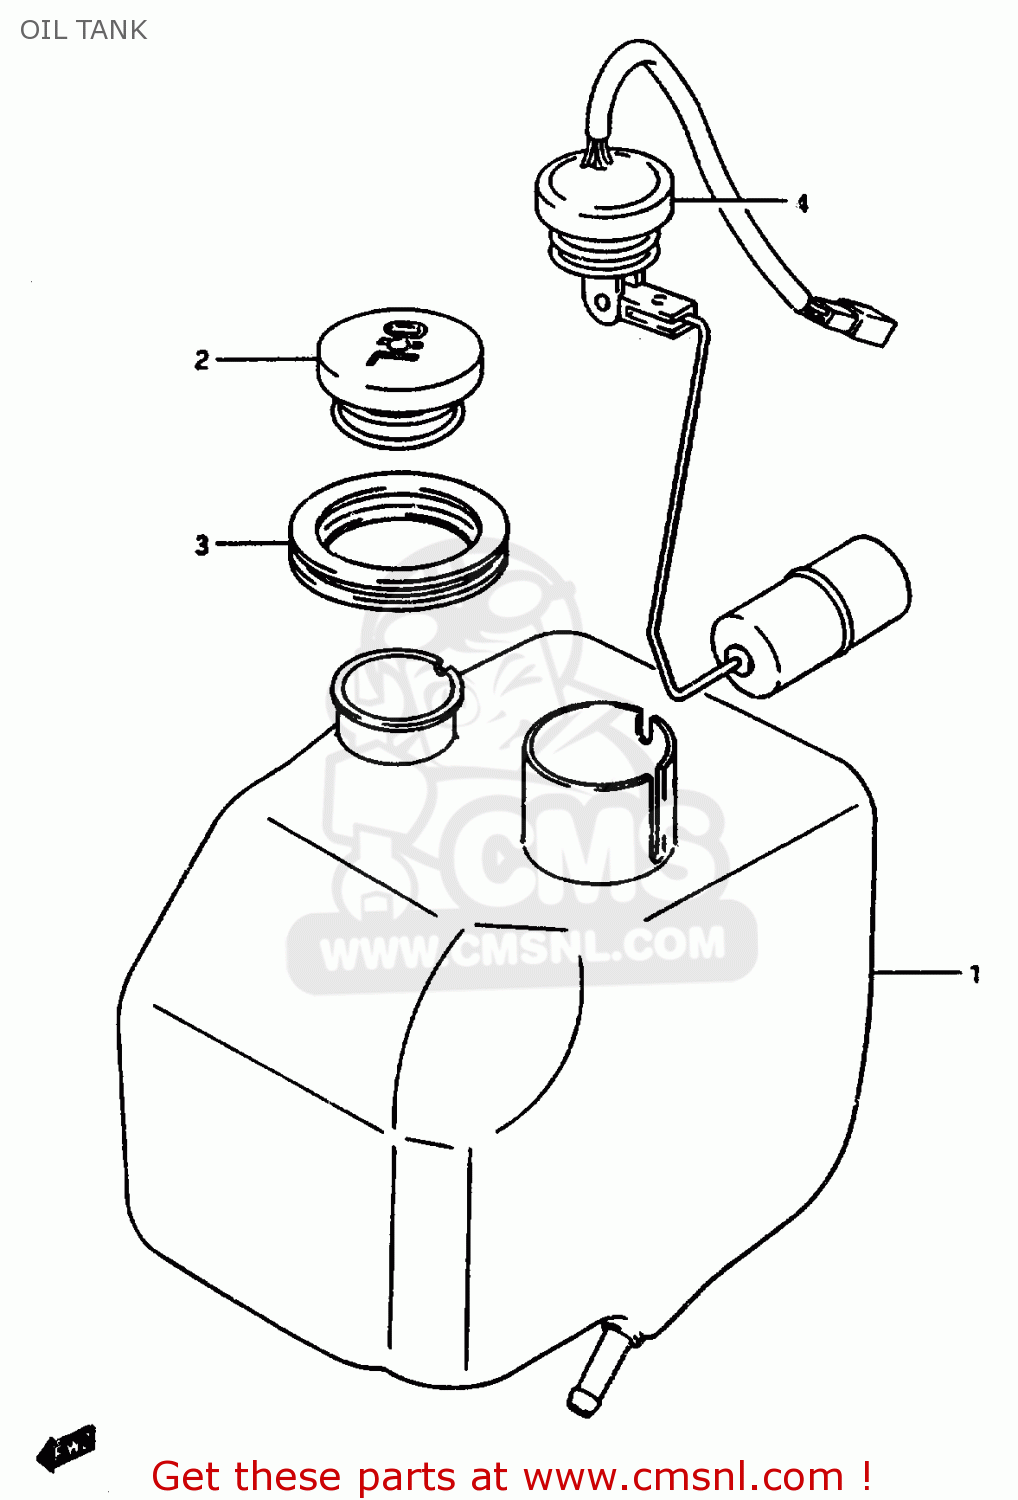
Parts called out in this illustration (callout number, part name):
1	TANK, OIL
2	CAP,OIL TANK
3	RUBBER,OIL TANK INLET
4	SWITCH ASSY,OIL LEVEL
